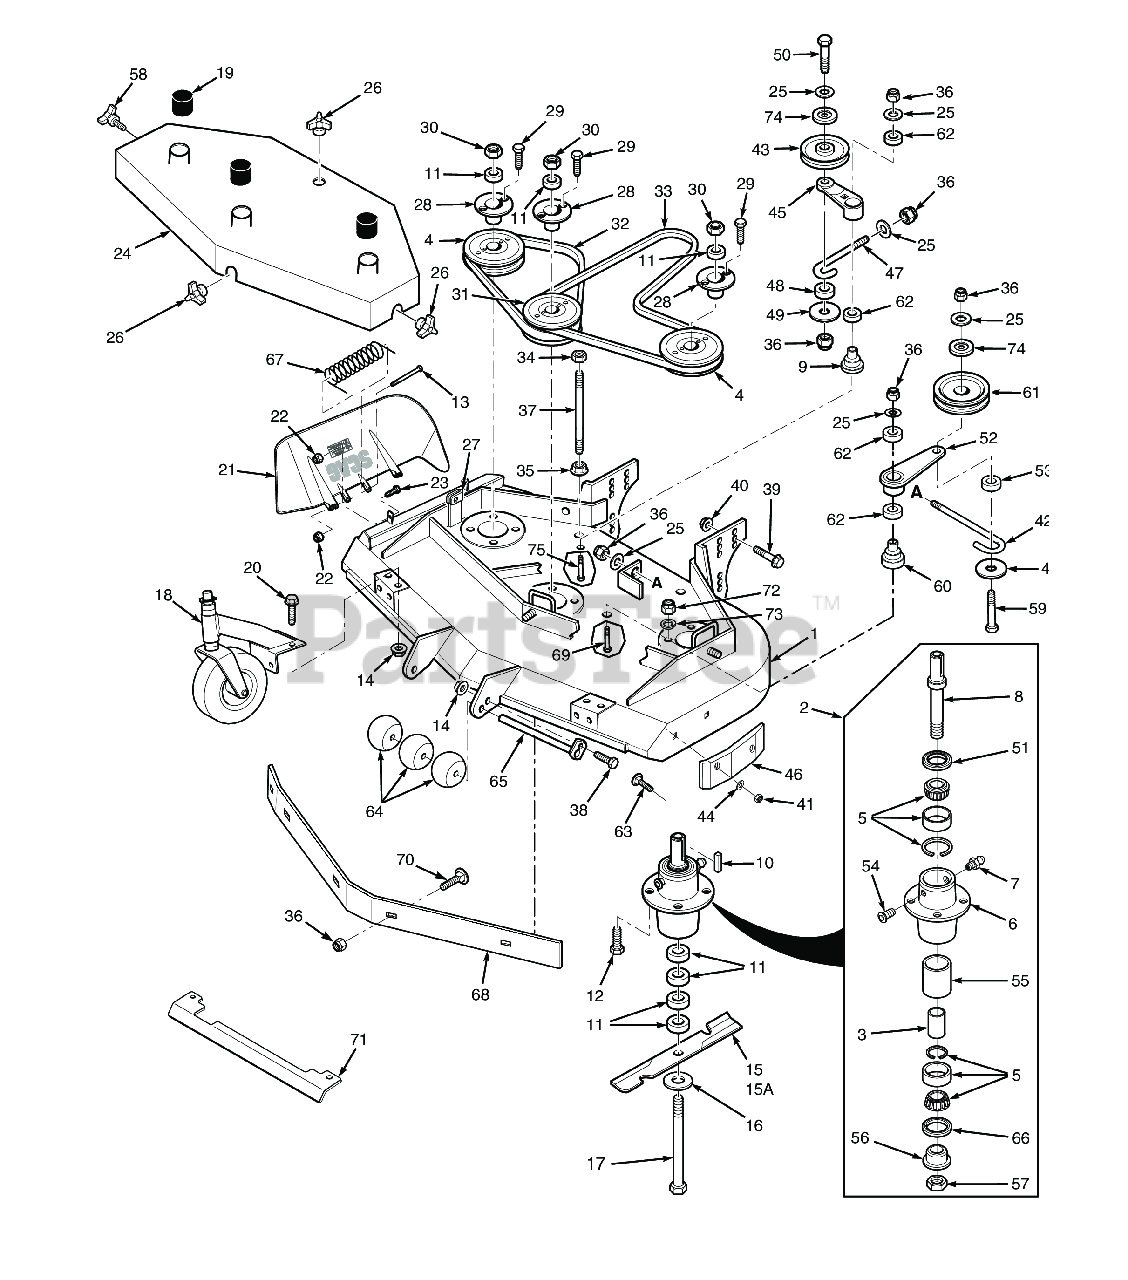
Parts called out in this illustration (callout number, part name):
1	Cutter Deck w/Decals
2	Cutter Spindle Assembly
3	SLEEVE, CUTTER SPINDLE
4	Pulley, 6.35 O.D. (Diesel Engine)
5	Tapered Bearing Set (Two Bearings W/Race)
6	Housing, Spindle
7	GREASE FITTING, STR. 1/4-28 SELF TAP.
8	Spindle Shaft, Tapered Brng
9	Idler Pivot
10	Key, 1/4 x 1/4 x 2.0"
11	Spacer, Cutter Blade - Small
12	Bolt, Hex Head 5/16-18 x 1-1/2" Grade 8
13	Bolt, 5/16-18 x 4-3/4" Hex Head
14	Nut, Serrated Flange 5/16-18 (Right Front Engine Mounting, Briggs and Kohler Only)
15	Cutter Blade, 21" Standard
15A	Cutter Blade, High Lift (61" Deck)
16	Flatwasher, 5/8-.688 x 1-3/4 x .134 HD
17	BOLT, HEX HEAD, 5/8-11 X 9-1/2 GR.5
18	Caster Assembly
20	Capscrew, 5/16-18 x .75 Serrated Flange Hex Head
21	Discharge Chute Advantage - Large
22	HEX NUT, ELASTIC STOP LOCK, 5/16-18
23	Bolt, Hex Head 5/16-18 x 1-1/2" (Right Front Engine Mounting, Briggs and Kohler Only)
24	Belt Cover (Incl. decals)
25	Flatwasher, 3/8 (.391 x .938 x .105 HD) Grade 8
26	WINGNUT, PLASTIC 3/8-16 X .875
27	U-Nut, 3/8-16 (short)
28	Hub, Tapered 1-1/8" Bore
29	Bolt, Hex Head 1/4-20 x 1" Grade 8 Black
30	Hex Locknut, Elastic Stop, 3/8-16
31	Pulley, Double Groove, 6.35/5.75 O.D.
32	BELT, RH BLADE DRIVE 61" DECK
33	BELT, BLADE DRIVE SLM 48
34	Bolt, Hex Head 3/8-16 x 1" Ser. Flg.
35	NUT, 3/8-16 SERRATED FLANGE HEX HEAD
36	HEX NUT, ELASTIC STOP LOCK, 3/8-16
37	Bolt, 5/16-18 x 1" Hex Head
38	Bolt, Heax Head 5/16-18 x 1" (48V / 52V)
39	Serr. Fl. Hex Head Capscrew, 1/2-13 x 1-3/4
40	Nut, Elastic Stop 1/2-13, (STT-52 & STTII-52)
41	Nut, Center Lock, 5/16-18(32)
42	J-Hook, Idler Pulley
43	IDLER PULLEY, "V" GROOVE
44	Flatwasher, 5/16-.344 x .688 x .065 (48V / 52V)
45	Idler Arm Assembly
46	Pad, Deck Wear
47	J-HOOK, IDLER PULLEY
48	SPACER, J PULL ROD
49	Flatwasher, 3/8 (.375 x 1-1/2" x 16 ga.)
50	Capscrew, Hex Head 3/8-16 x 2-1/2"
51	SEAL, 2.00 O.D. X 1.50 BORE
52	Idler Arm Assy.
53	SPACER, J-PULL ROD
54	RELIEF FITTING, TAPERED BEARING SPINDLE
55	Spacer, Outside, Cutter Spindle
56	SPINDLE BUSHING, BOTTOM
57	Nut , Spec ial 1 -1/ 1 6 - 1 8
58	Knob, w/stud 3/8-16 x 1-1/4"
59	Capscrew, Hex Head 3/8-16 x 3-3/4"
60	Pivot, Idler - Short
61	Idler Pulley, Belt Clutch
62	BEARINGS, BALL, NEUTRAL RETURN
63	Bolt, 5/16-18 x .75 RHSN Carriage
64	Wheel, Anti-Scalp
65	Shaft Weldment, Guide Roller
66	Seal, 2.00" O.D. x 1.625" Bore
67	Spring, Discharge Chute
68	Baffle Custom-Cut, 61V (7-Position)
69	Capscrew, Hex Head 3/8-16 x 3.25"
70	Carriage Bolt, 3/8-16 x 1.0"
71	Heatshield, 20" Large Frame
72	Lock Nut, 5/16-18 Elastic Stop Grade 8
73	Lockwasher, 5/16 (.317 x .586 x .078) Helical Spring
74	Quick Pin, 5/16" Dia.
75	Capscrew, Hex Head 3/8-16 x 2.75"
